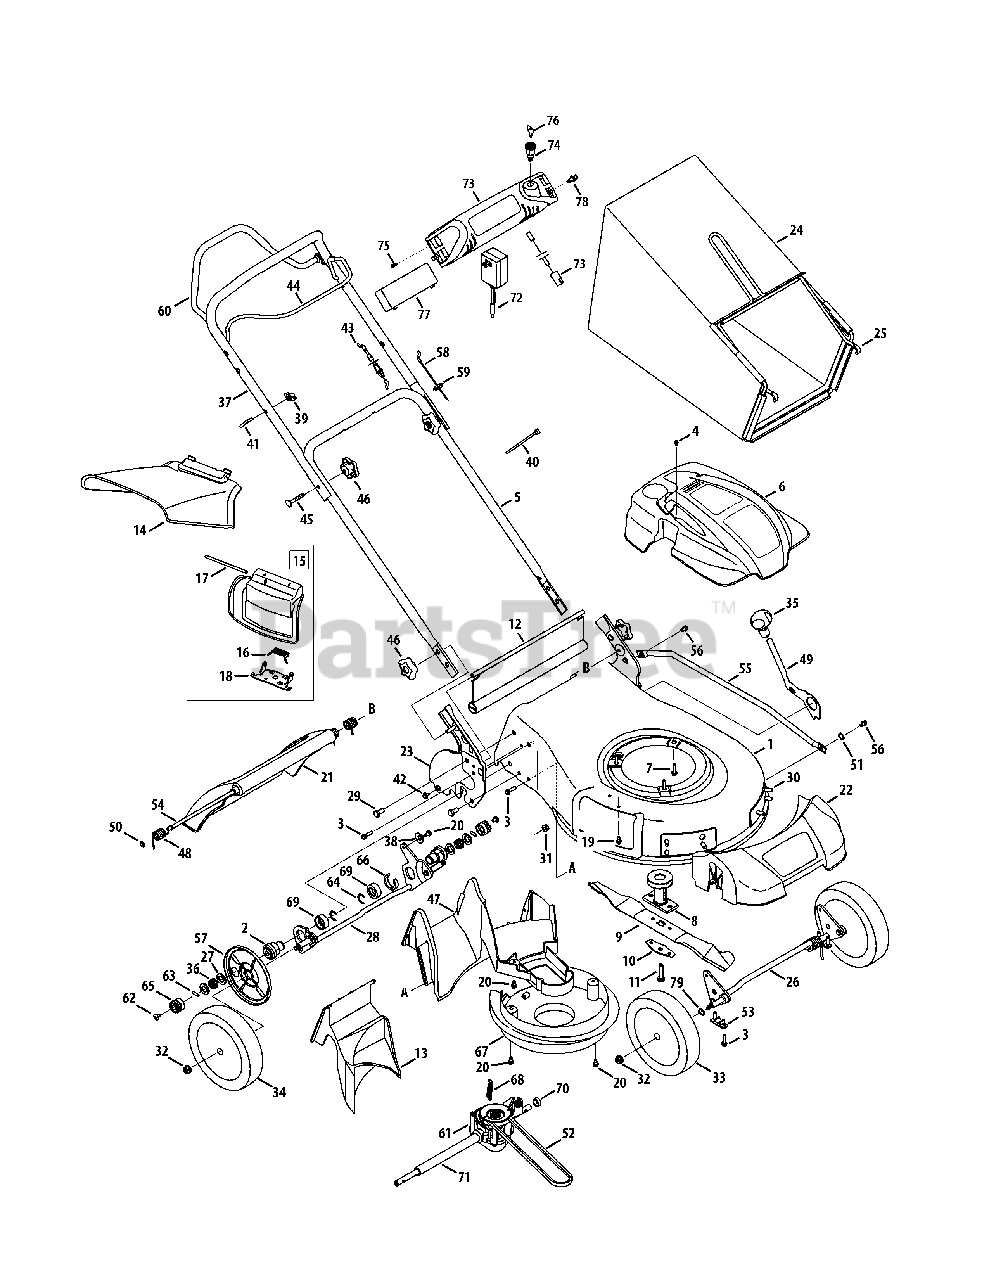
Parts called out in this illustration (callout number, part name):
2	Transmission Support Bearing
3	Screw, 1/4-15 x 1.000
4	Screw, HL, #12-16 x 1.00
5	Lower Handle
6	Engine Shroud
7	Screw, 3/8-16 x 1.00
8	Blade Adapter
9	Mulching Blade
10	Blade Bell Support
11	Screw, 3/8-24 x 1.50
12	Trailing Shield
13	Rear Mulch Plug
14	Side Discharge Chute
15	Mulch Plug (Incl. 16-18)
16	Torsion Spring
18	Chute Deflector Adapter
22	Front Cover
23	Handle Bracket - RH
23	Handle Bracket - LH
25	Grass Bag Frame
26	Front Bracket Assembly
27	Washer, Flat, .508 x 1.00 x .020
28	Self Propelled Bracket Ass’y
29	Hhcs, 5/16-18 x .625
30	Screw, 5/16-14 x .750
31	Nut, Flange Lock, 5/16-18
32	Nut, Flange Lock, 3/8-16
33	Front Wheel
34	Rear Wheel
36	Wave Spring
37	Upper Handle
38	Washer, Bell, .340 x .872 x .060
40	Cable Tie
41	Rope Guide
42	Screw, #10-16 x .500
43	Control Cable
44	Blade Control
45	Bolt Carriage, 5/16-18 x 2.0
47	Rear Baffle
48	Door Torsion Spring - RH
48	Door Torsion Spring - LH
49	Spring Lever
51	Wshr, Wave, .385 ID x .598 OD
53	Bushing, Lock, .505 Dia. X .62
54	Rear Door Pivot Rod
55	Cross Bracket
56	Scr., Shldr., 1/4-20 x .50
57	Wheel Dust Cover
58	Drive Cable
60	Drive Control
61	Transmission
62	Screw, 1/4-20 x .390
63	Dowel Pin
64	Retainer Ring
65	Spur Gear - RH
65	Spur Gear - LH
66	Spacer, Clip
67	Engine Baffle
68	Exten. Spring, .429OD x 2.515
69	Bearing Support Spacer
70	Sleeve Spacer, .550ID x .340 Lg.
71	Sleeve Spacer, .550ID x 7.97 Lg.
72	Battery Charger
73	Electric Start Harness Assembly
74	Key Switch
75	Screw, #10-16 x .750
77	Battery
79	Washer, Wave, .510 x .750 x .017
